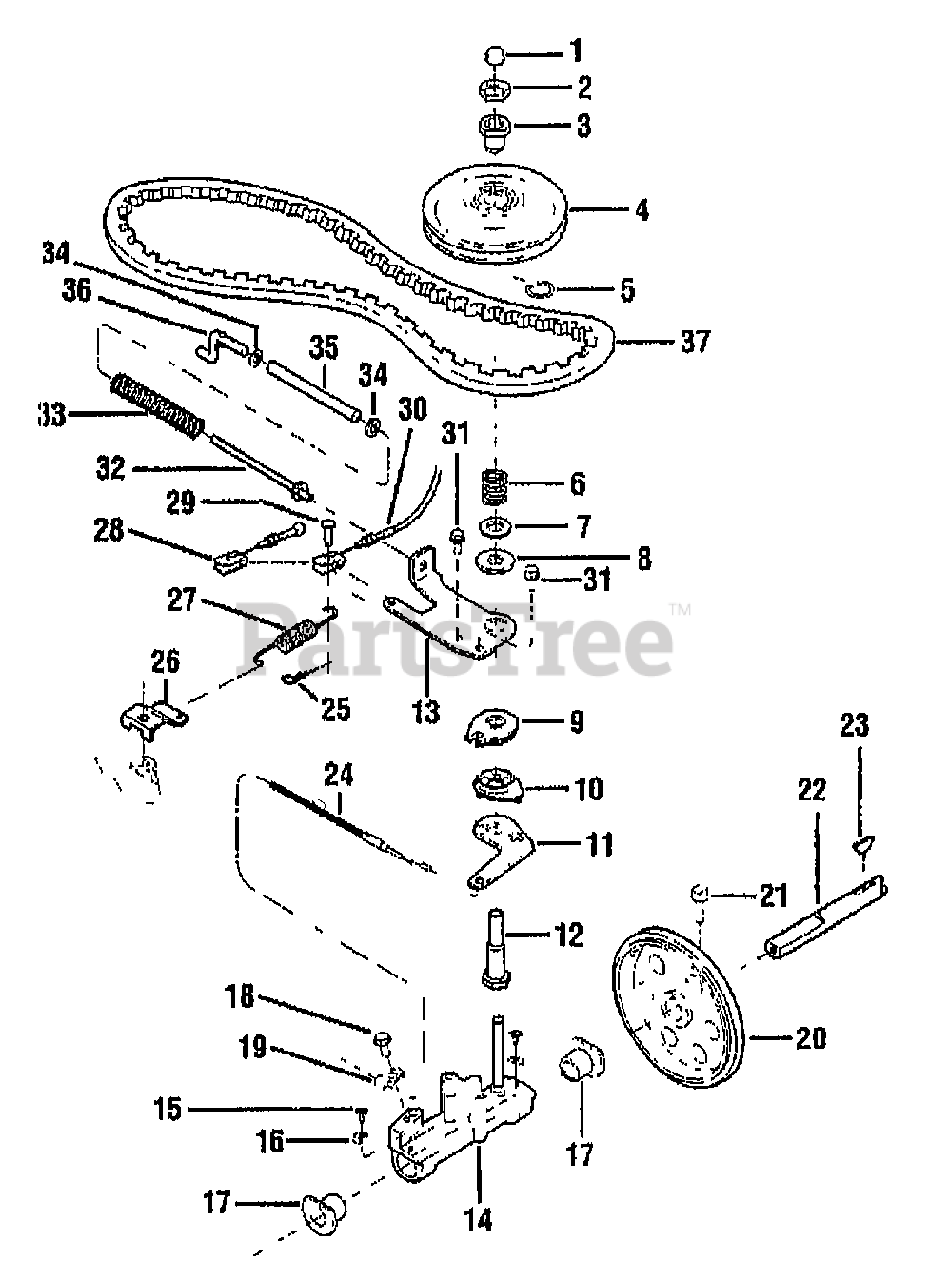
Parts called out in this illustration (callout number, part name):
1	PLUG-CAP VPC
2	NUT-H/LK 1/2-20
3	NUT-HEX 1/2-20X.5
4	ASSM-SHEAVE W/BEARING
5	RING-BOWED EXT .669 ID
6	SPRING-COMPRESSION
7	WASHER-1.0X.632X.03 ZP
8	WASHER-.605X1.102X.08
9	PLATE-RAMP UPPER
10	PLATE-RAMP LOWER
11	ARM-CONTROL
12	SLEEVE-ADJUST
13	PLATE-ANCHOR PLATED
14	ASSM-CARRIER W/STUD
15	SCR-TORX HD
16	CLIP-BRG RETAIN BLK OXIDE
17	BEARING-CARRIER
18	SCR-HW M10-24 THRFRM
19	CLAMP-HOUSING
20	DISC-DRIVE/FRICTION
21	SCR-SET SQ 1/4-20 W/NYLOC
22	AXLE-DRIVE ROUND NGMM
23	KEY-WOODRUFF .125X.5
24	CABLE-CONTROL DRIVE
25	PIN-CLIP .08
26	BRKT-SPRING MOUNT PLATED
27	SPRING-SPEED CONTROL
28	CABLE-SINGLE SPD CONTROL {34021}
29	PIN-SPEED CONTROL
30	ASSM-ARM CONTROL
31	SCR-FLANGE 1/4-20X3/4 GR5
32	ROD-BELT ADJ
33	SPRING-COMPRESSION
34	WASHER-FLAT 1/4 SAE
35	SLEEVE-BELT
36	KIT-SVC ANCHOR Z ROD
37	BELT-V NGMM
